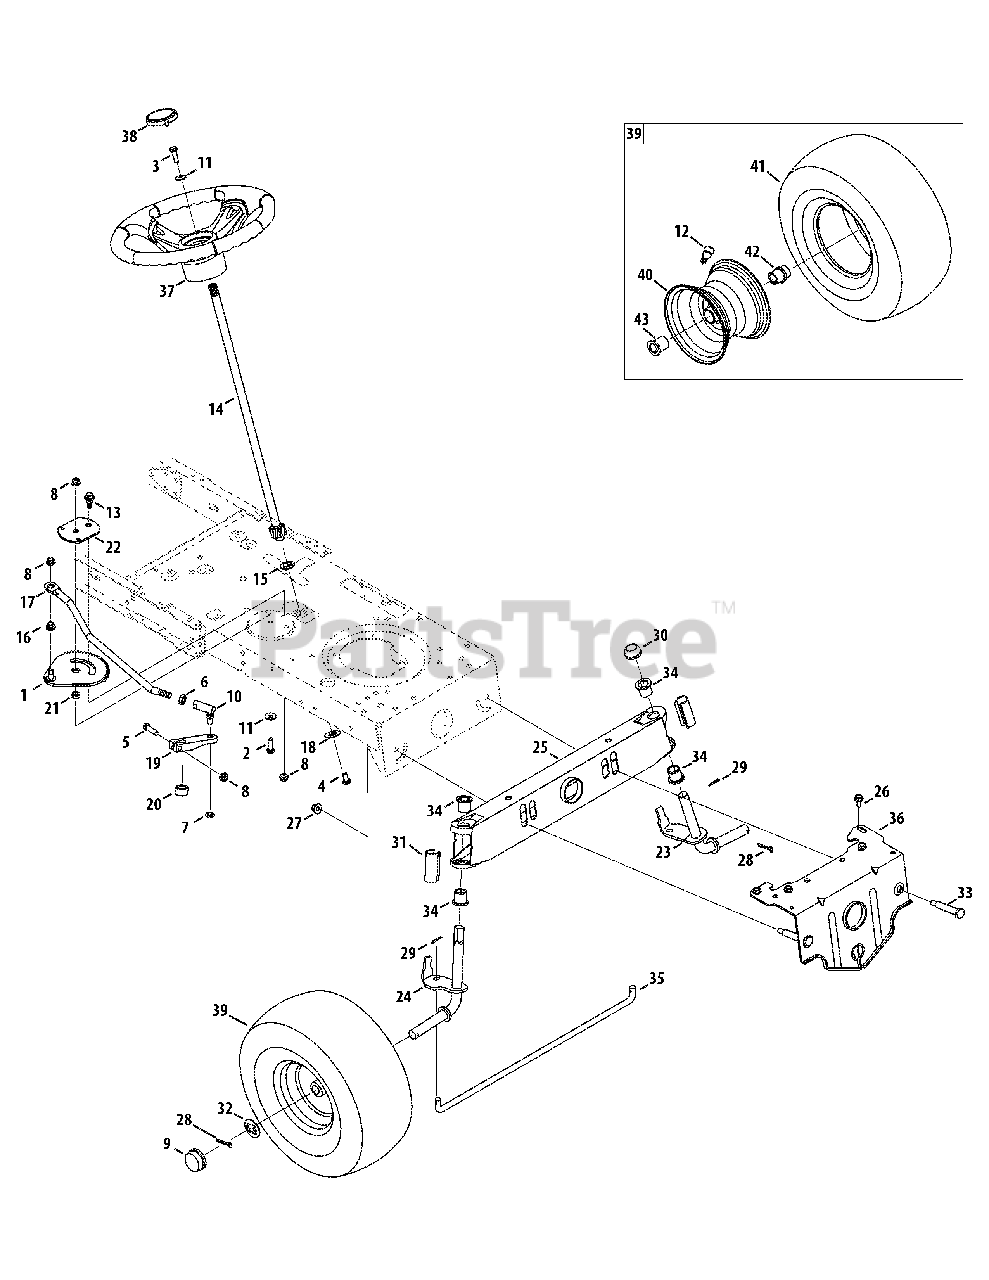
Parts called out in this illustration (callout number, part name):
1	Gear Assembly, Steering
2	Screw, 5/16-18, 1.00, Gr5
3	Screw, 5/16-18, 1.00, Gr5, Lock
4	Screw, Mach, 5/16-18, 0.750
5	Screw, 5/16-18, 1.75, Gr5
6	Nut, Jam, 7/16-20, Gr2
7	Nut, Jam Lock, 3/8-24
8	Nut, Flange Lock, 5/16-18, Grf
9	Hub Cap
10	Ball Joint, 7/16-20, Lock
11	Washer, Bell, .340 x .872 x .060
12	Valve Stem
13	Shoulder Screw, 5/16-18
14	Steering Shaft, 5/8 Spline x 21.86
15	Bearing, Flange, Hex 5/8
16	Plastic Bushing .375 ID x .05 OD
17	Drag Link, Steering
18	Cap, 1.25 x .16
19	Steering, Block
20	Spacer, .710 ID x .125 OD x .56
21	Spacer, .322 ID x .625 OD x .21
22	Stabilizer Plate, Gear Segment
23	Axle Assembly LH
24	Axle Assembly RH
25	Pivot Bar Axle Assembly
26	Screw, 5/16-18, 0.750
27	Nut, Flange Lock, 3/8-16, GrF
28	Pin, Cotter, 5/32, 1.25
29	Pin, Cotter, 1/8 x 0.75
30	Push Cap, 3/4
31	Axle Cap
32	Washer, Flat, .781 x 1.59
33	Screw, Shlder, .500 x 2.380, 3/8-16
34	Flange Bearing
35	Tie Rod
36	Pivot Bar Bracket
37	Steering Wheel, Standard Grip
38	Cap, Steering Wheel (Crafts. logo)
39	Wheel Assembly
40	Rim
41	Tire, 15 x 6 x 6 Sq. Shoulder
42	Flange Bearing
43	Flange Bearing
